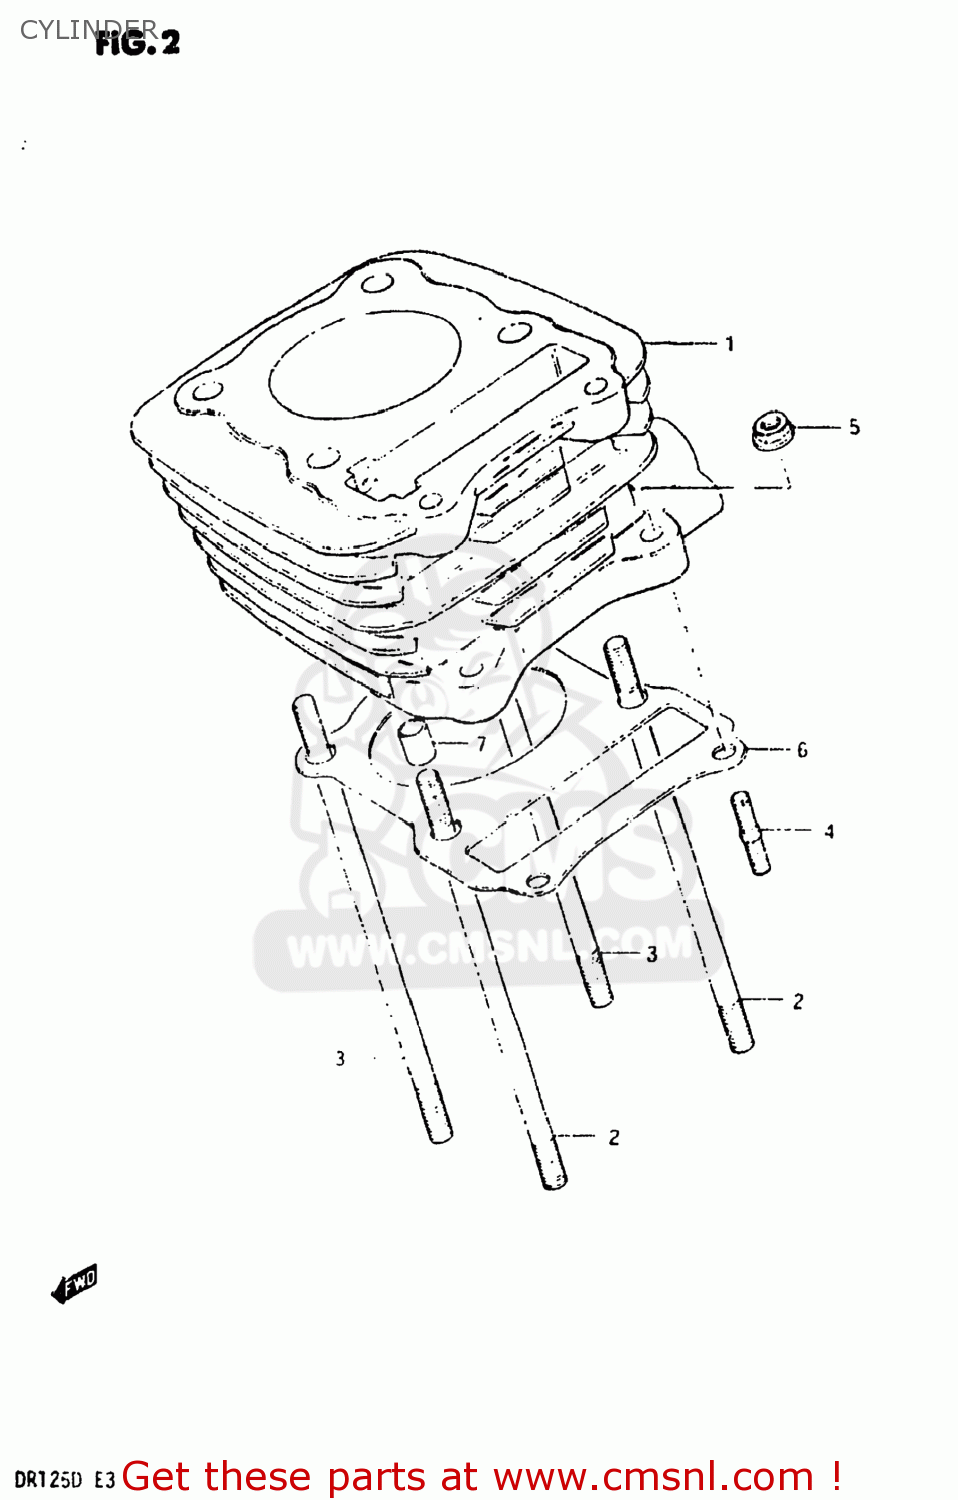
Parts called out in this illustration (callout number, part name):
1	CYLINDER
2	BOLT,STUD
3	BOLT,STUD
4	STUD 6X25
5	NUT
6	GASKET,CYLINDER (MCA)
7	PIN
